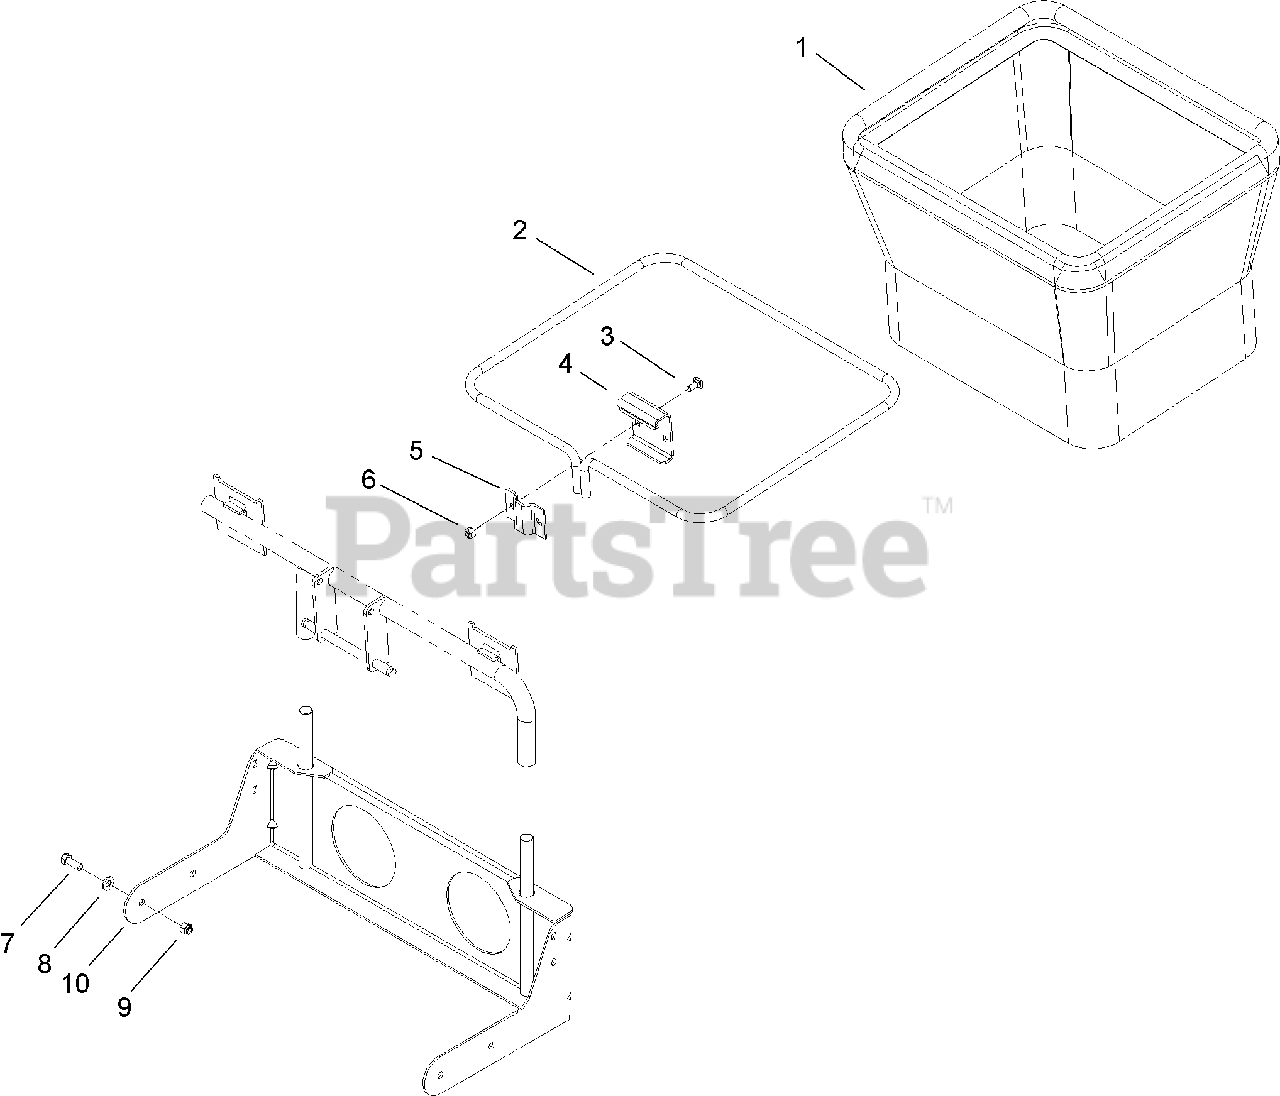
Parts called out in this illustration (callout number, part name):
2	FRAME-BAG
3	BOLT-CARR
4	HANGER-BAG
6	NUT-LOCK, NI
7	SCREW-HH
8	WASHER-FLAT
9	NUT-LOCK, NI
10	BAGGER SUPPORT ASM
